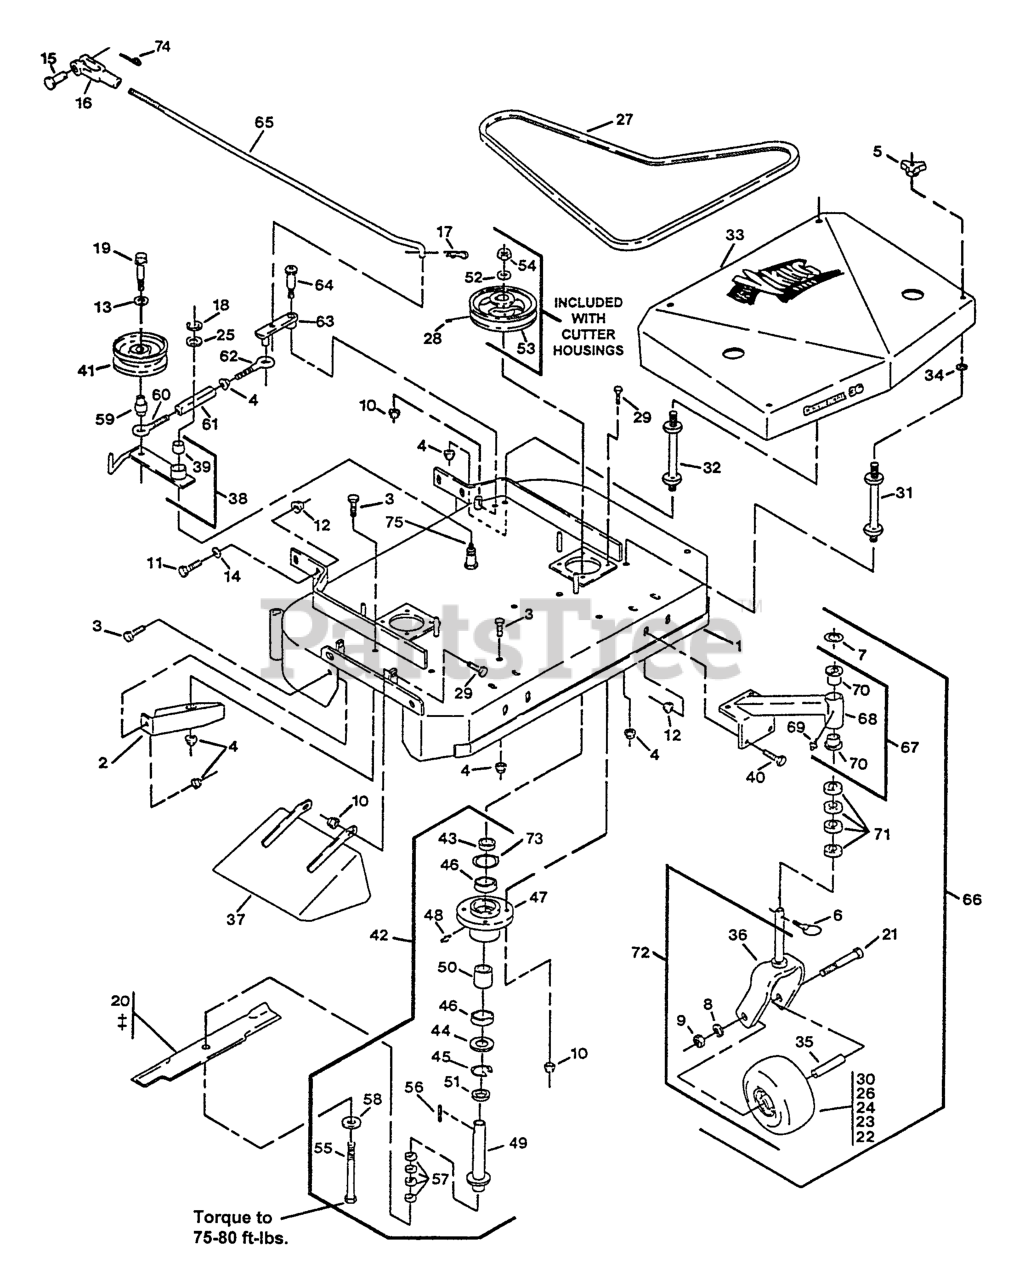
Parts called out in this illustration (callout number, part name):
2	BAFFLE-DOGLEG
5	KNOB-3 PRONG
7	WASHER-FLAT
15	PIN-CLEVIS
16	YOKE-ADJUSTABLE
17	PIN-COTTER
22	BUSHING
23	BEARING
25	WASHER-SPINDLE
27	BELT,DECK DRIVE
28	SCREW-SET
31	STUD-SHIELD, BELT (SHORT)
32	STUD-SHIELD, BELT (LONG)
37	Chute
39	BEARING,POWDERED METAL
42	ASM,HOUSING CUTTER
44	SEAL,DUST
45	RING,SNAP WLDS N5000-244
46	BEARING,HD SPINDLE
47	HOUSING,CUTTER
50	SPACER,BRG/BRG
51	SPACER,BEARING &SPINDLE
52	WASHER-RETAINER, SHEAVE
55	SCREW-CAP, HH
58	WASHER-SPRING
59	BUSHING-ENGAGEMENT
60	EYEBOLT-THREAD, LH
61	BODY-TURNBUCKLE
62	EYEBOLT-THREAD, RH
64	BOLT,SHLDR KSKH
65	ARM-LINKAGE, ASSIST
66	CASTER/MOUNT ASM
67	SUPPORT ASM
70	BEARING-FLANGED
71	SPACER-CASTER
